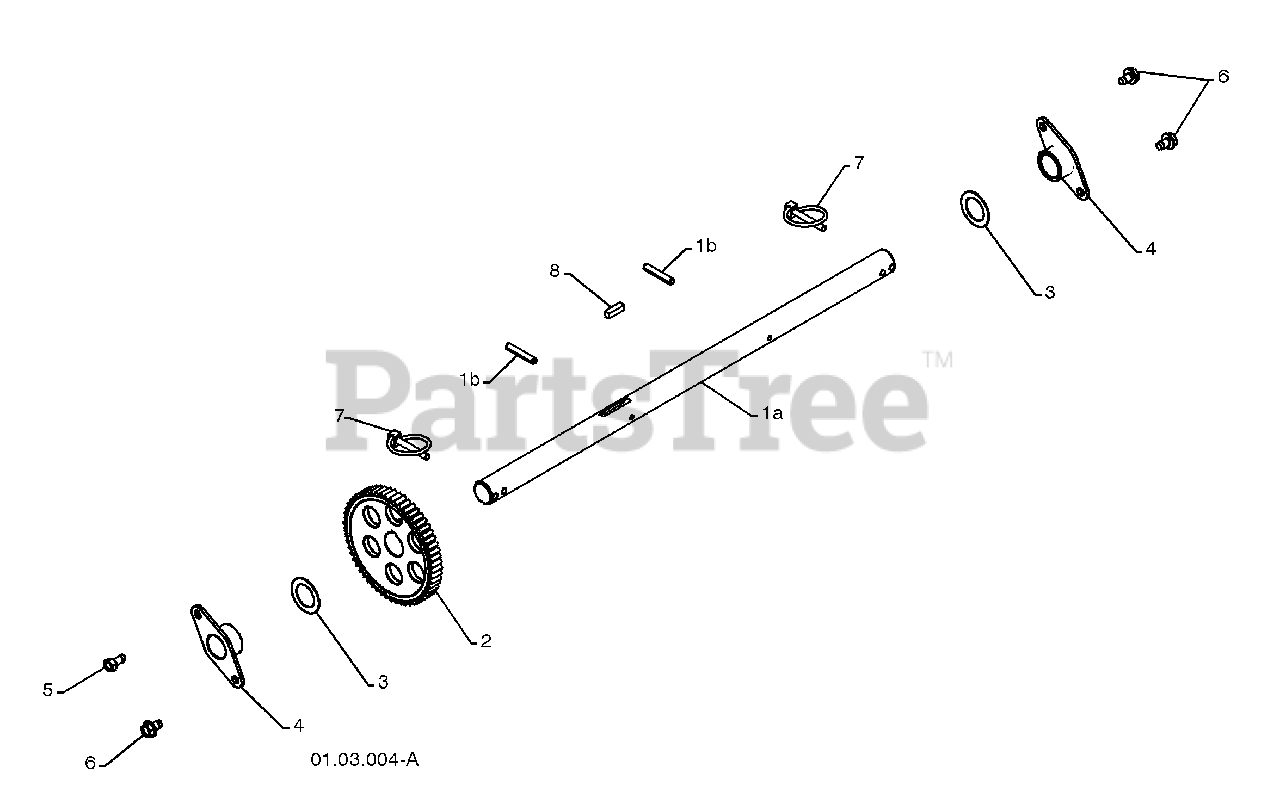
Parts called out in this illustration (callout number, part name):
1	AXLE ASSEMBLY
2	GEAR
3	THRUST WASHER
5	SCREW 5/16-18 X .625
6	BOLT 5/16-18 X .500
8	SQUARE KEY
